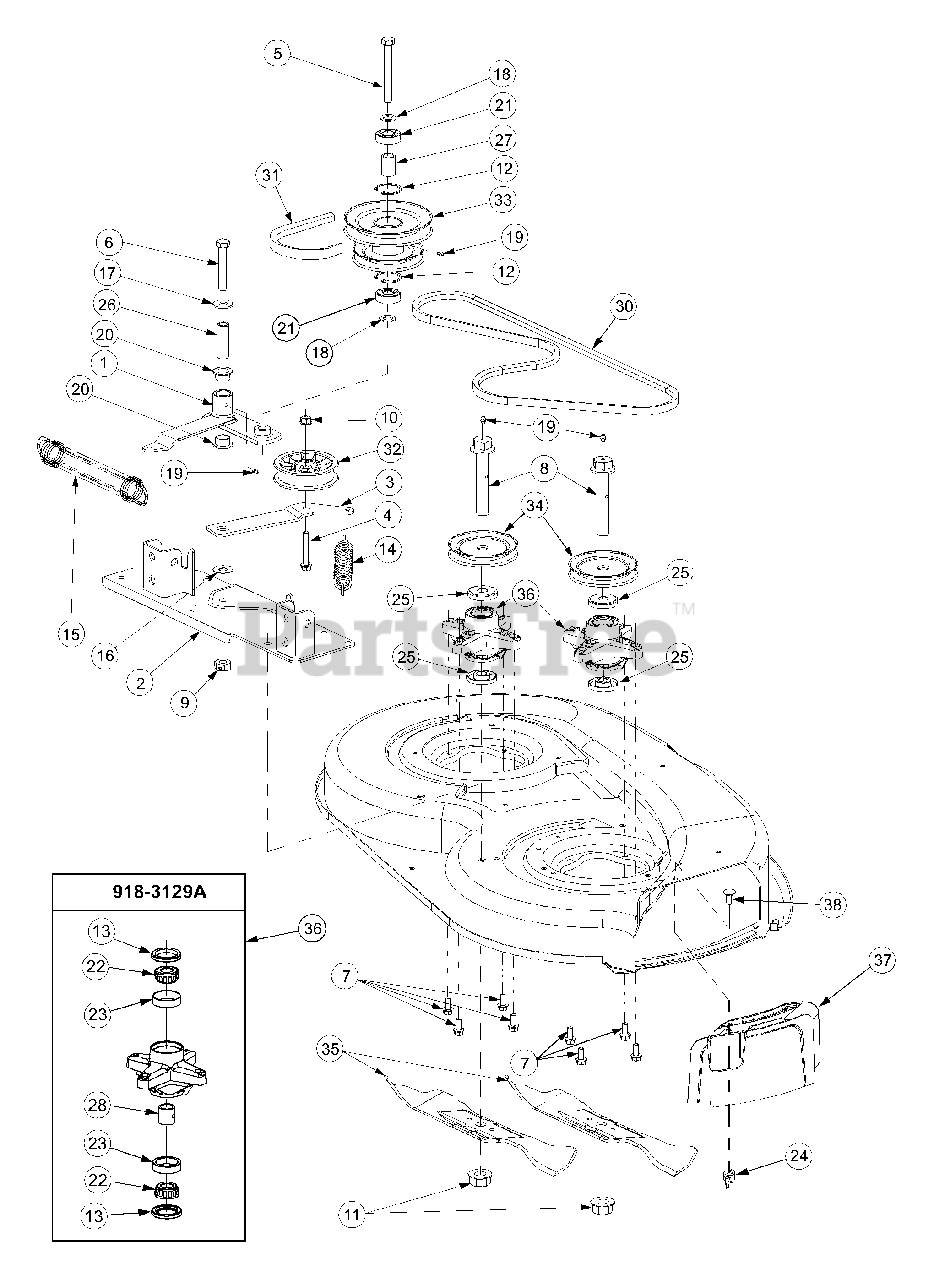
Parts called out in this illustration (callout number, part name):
4	Screw, Hex Cap, 3/8-16 x 1.5 GR5
5	Screw, Hex Cap, 5/8-18 x 3.0 GR5
6	Screw, Hex Cap, 1/2-20 x 3.0 GR8
7	Screw, Hex Wsh Hd Tap, 5/16-18 x .75
8	Bolt, Spindle, 3/4-16 x 4.25
9	Nut, Hex Center Lock, 1/2-20
10	Nut, Hex Flange Lock, 3/8-16
11	Nut, Hex Flange, 3/4-16
12	Snap Ring, Internal
13	Seal, Oil, 1.25 x 1.874 x .25
14	Spring, Extension, .88 x 6.12
15	Spring, Extension, 1.25 x 8.15
16	Washer, Flat, .531 x 1.25 x .036
17	Washer, Flat, .531 x 1.25 x .100
18	Washer, Flat, .65 x 1.25 x .075 Hdn.
19	Fitting, 3/16 Drive Lube
20	Bearing, Flange, 3/4 ID x .53 Lg
21	Bearing, .625 ID x 1.574 OD x 470
22	Cone, Bearing
23	Cup, Bearing
24	Nut, Wing, 1/4-20
25	Spacer, Deck Spindle
26	Spacer, Idlr Brkt .50 ID x .75 OD x 2.25
27	Spacer, Pulley .635 ID x .88 OD x 1.25
28	Spacer, Bearing, .780 x .963 x .777
30	Belt, Spindle, A-Section x 59 Lg
31	Belt, PTO, B-Section x 111.2 Lg
32	Pulley, Flat Idler, 3.5 OD
33	Pulley, Double
34	V-Pulley, 4.0 Dia
35	Blade, 3 In One, 19.38 Lg
36	Spindle, Blade
37	Plug, Mulch
38	Screw, Carriage, 1/4-20 x .62
